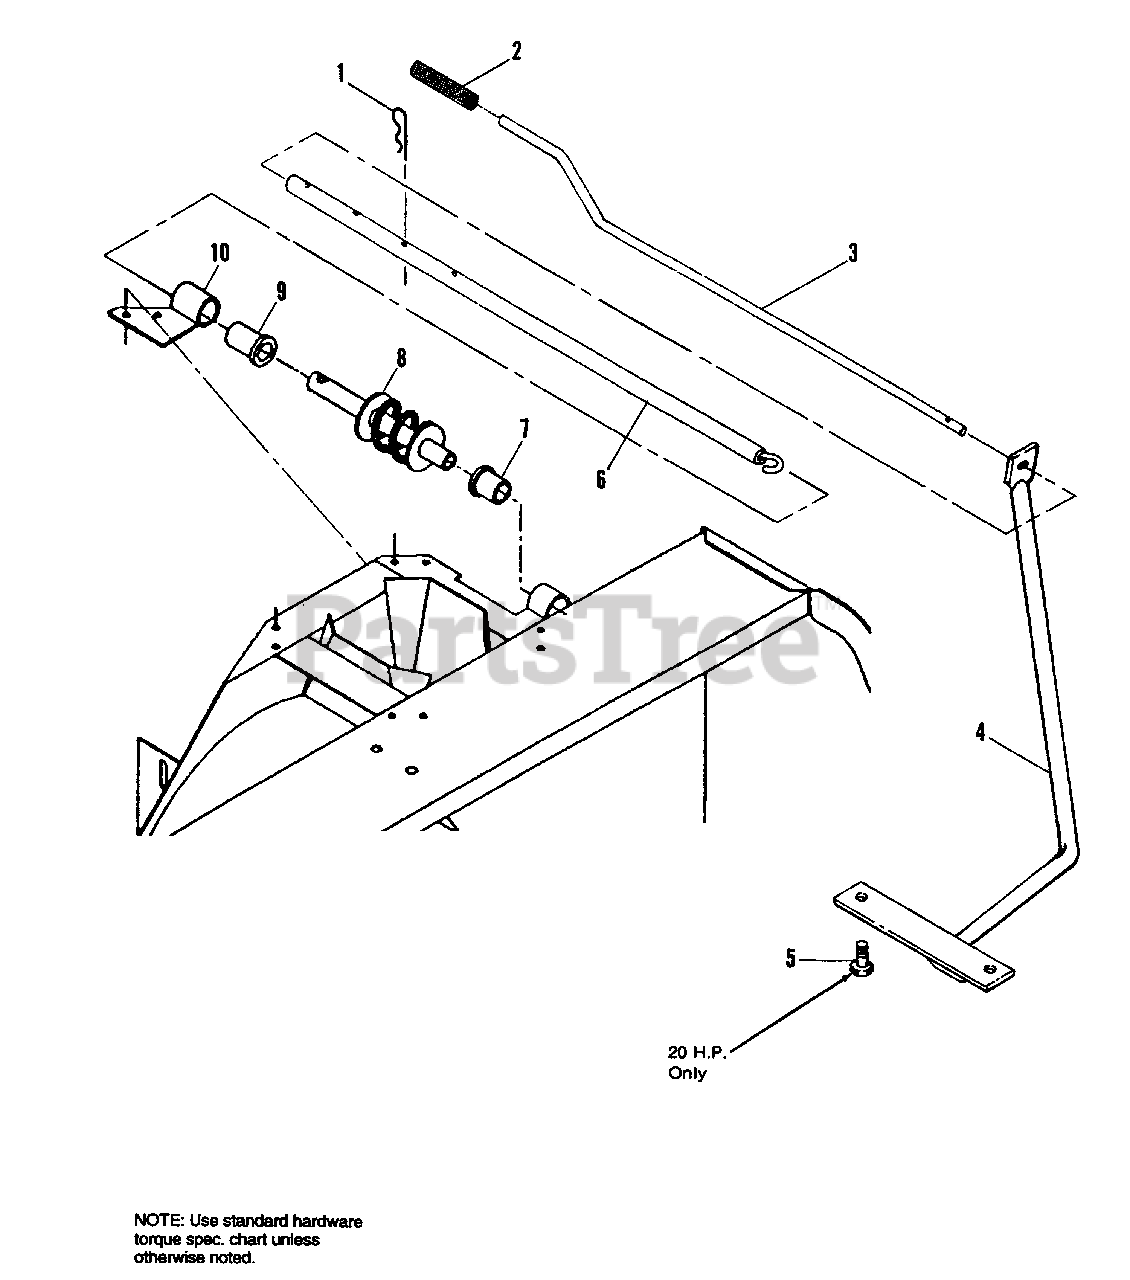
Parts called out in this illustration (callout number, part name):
1	CLIP, Hair Pin, 1/8 x 2-9/16
2	GRIP, Handle
4	SUPPORT ASSY., Spout Rotator
5	CAPSCREW, Hex Hd., 5/16-14 x 1-1/2, Gr. 5
6	TUBE, Upper Rotation
7	BUSHING, Plastic w/Flange
8	WORM, Rotation
9	BUSHING, Plastic w/Flange
10	SUPPORT, Rotation, Worm
